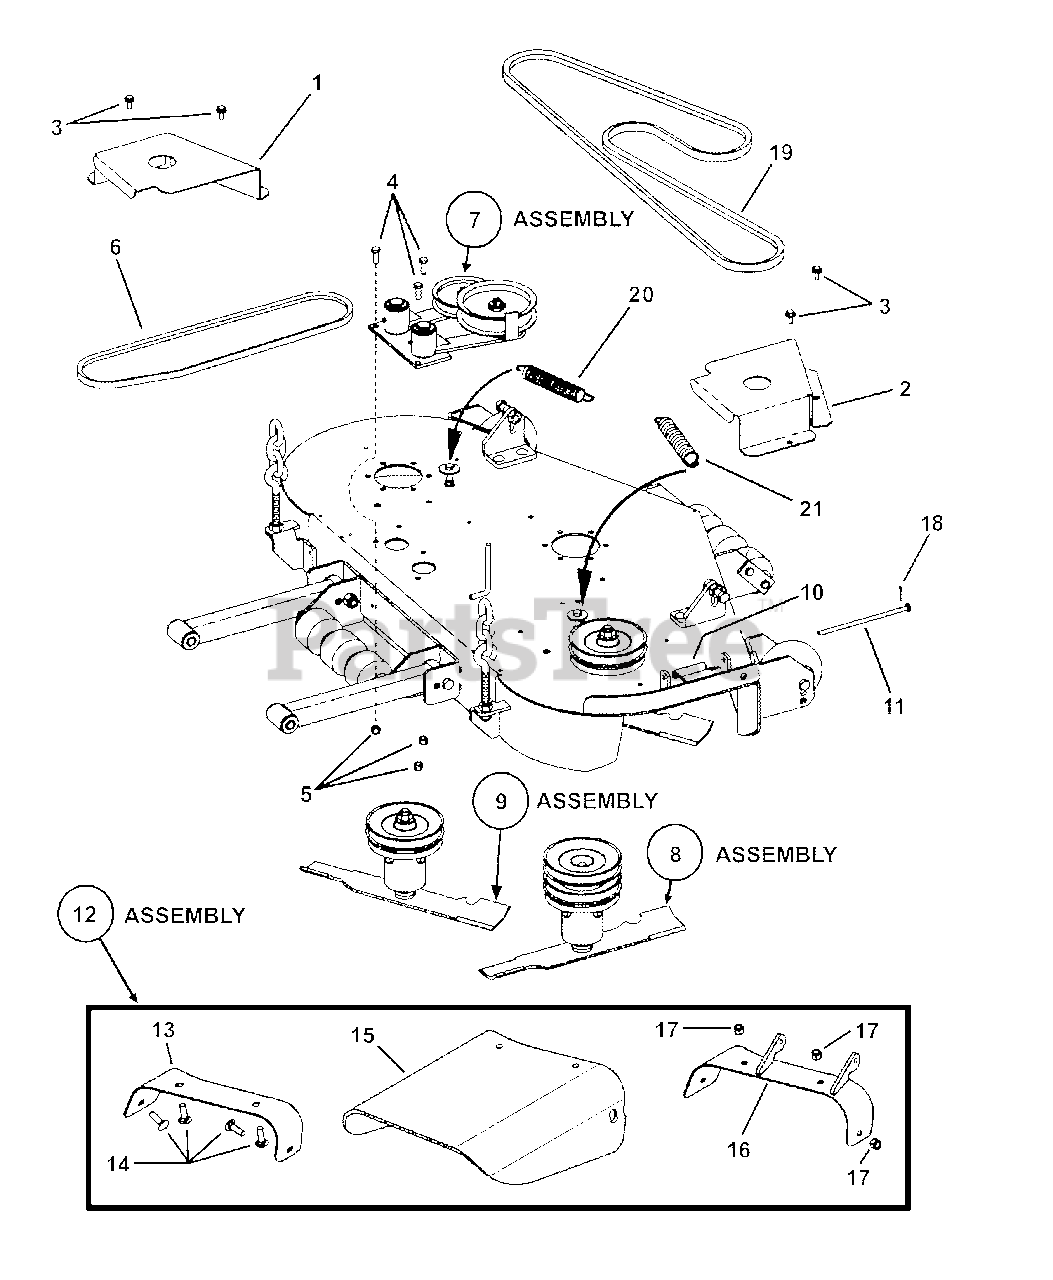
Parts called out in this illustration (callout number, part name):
1	BELT COVER, Left Hand
2	BELT COVER, Right Hand
3	SCREW, 5/16-18 x 5/8" Hex Washer Self-Tap
4	BOLT, 3/8-16 X 1" GD5 CZ
5	NUT, 3/8-16 HEX NYLON LOCK
6	BELT, Primary (HB Section, 91.30" effective length)
7	ASSEMBLY, Idler
8	ASSEMBLY, Center Spindle
9	ASSEMBLY, Spindle
10	SPRING, Chute
11	PIN, Chute Hinge
12	ASSEMBLY, Discharge Chute
13	DEFLECTOR, Bottom
14	BOLT, 3/8-16 x 1-1/4" Square Neck Carriage, GR 5
15	CHUTE, Rubber 48"
16	WELDMENT, 48" Chute
17	NUT, 3/8-16 HEX NYLON LOCK
18	PIN, 3/32 x 1" Cotter
19	V-BELT, Secondary, 48" (HB Sect. 109.75" effective length
20	SPRING, Idler (1.17" O.D. x 7.5" long)
21	SPRING, Idler Primary (1.25" O.D. x 10" long)
